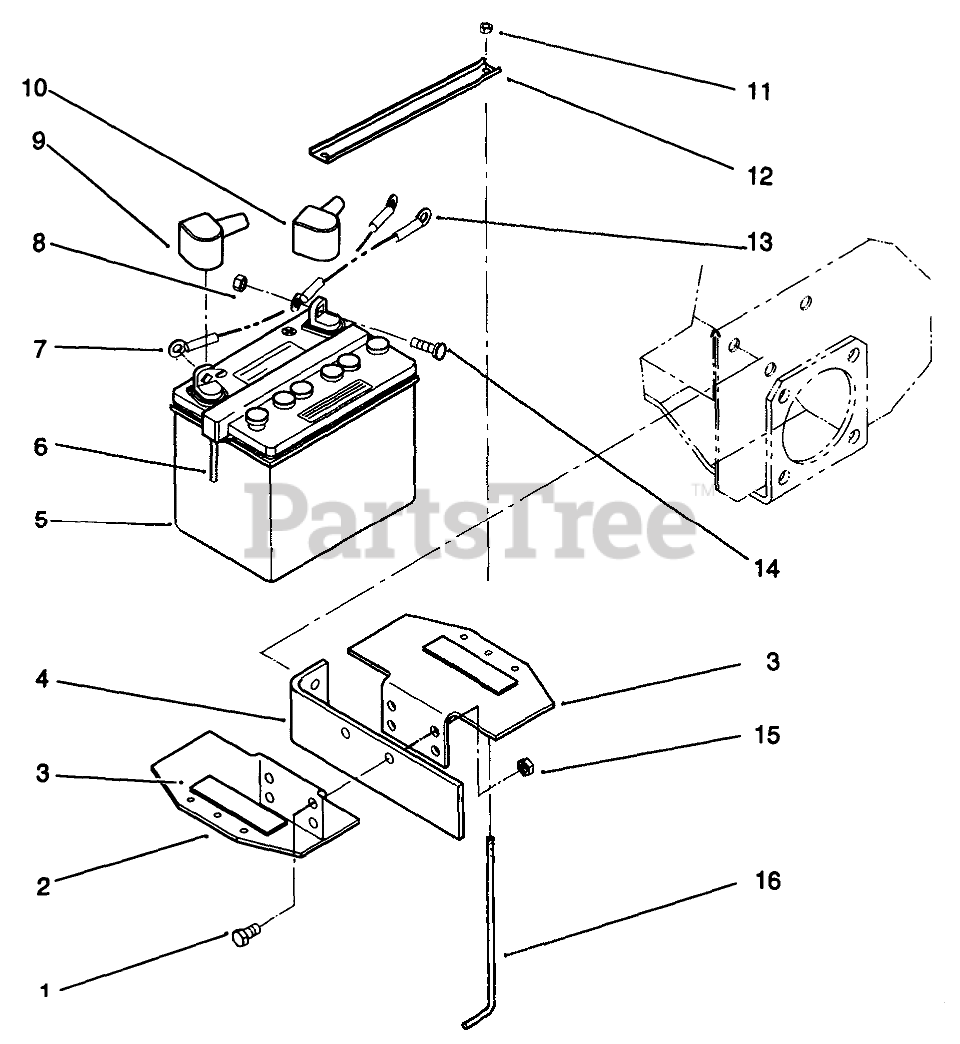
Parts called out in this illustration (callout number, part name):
1	SCREW-HH
2	Holder-Battery
3	PAD-TANK, FUEL
4	Frame-Carrier (Ref.)
5	Battery
6	TUBE-VENT
7	CABLE-BATTERY, NEGATIVE
8	NUT-KEPS
9	Boot-Terminal
10	BOOT-TERMINAL, RED
11	NUT-LOCK, NI
12	BATTERY STRAP R/B
13	WIRE ASM
14	BOLT-CARR
15	NUT-LOCK, NI
16	ROD-SUPPORT, BATTERY
